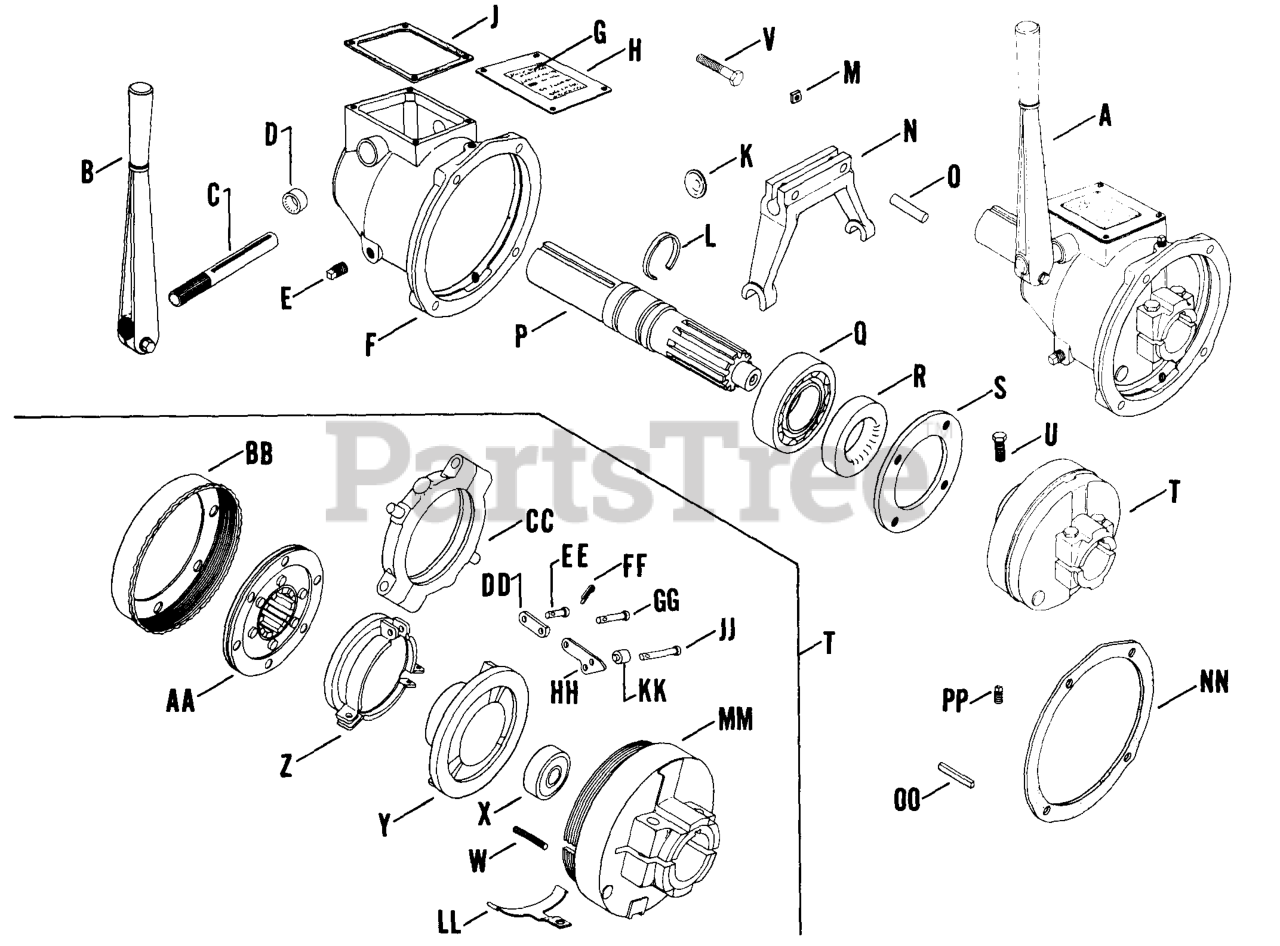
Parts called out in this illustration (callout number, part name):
A	CLUTCH - USE 48 239 02
B	LEVER - DISCONTINUED
C	SHAFT - DISCONTINUED
E	PLUG,PIPE 1/4 NPTF SQUARE HD USE 25 139 53-S
F	HOUSING - DISCONTINUED
H	COVER - DISCONTINUED
J	GASKET - DISCONTINUED
K	PLUG - USE X-230-20
L	RING - DISCONTINUED
N	YOKE - USE 24 471 01
P	SHAFT - DISCONTINUED
Q	BEARING - DISCONTINUED
S	PLATE - DISCONTINUED
T	CLUTCH - DISCONTINUED
U	Screw (Discontinued--Not Available)
W	SPRING - DISCONTINUED
X	BEARING
Z	SLEEVE - DISCONTINUED
AA	MEMBER - DISCONTINUED
BB	RING - DISCONTINUED
DD	LINK - DISCONTINUED
GG	PIN - DISCONTINUED
HH	LEVER - DISCONTINUED
JJ	PIN - DISCONTINUED
KK	ROLLER - DISCONTINUED
MM	HOUSING - DISCONTINUED
OO	KEY - DISCONTINUED
PP	PLUG-DISCONTINUED
